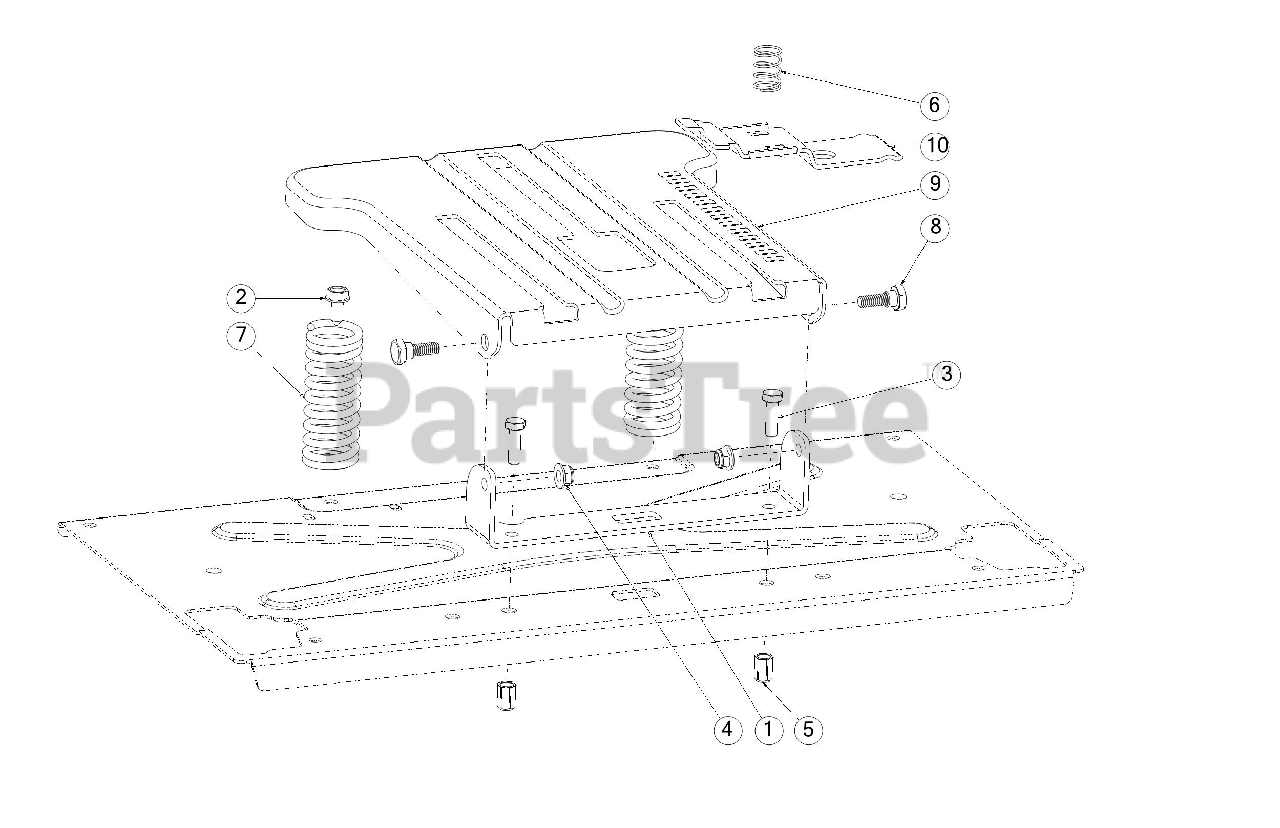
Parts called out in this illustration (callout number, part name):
1	SEAT PIVOT BRACKET
2	SCREW 5/16-18 X .750
3	SCREW 5/16-18 X 1.00 GR5
4	FLANGE LOCK NUT 5/16-18
5	NUT RIVET 5/16-18
6	COMPRESSION SPRING
7	COMPRESSION SPRING
8	SHOULDER SCREW .437
9	SEAT MOUNTING BRACKET
10	SEAT ADJUST LEVER
